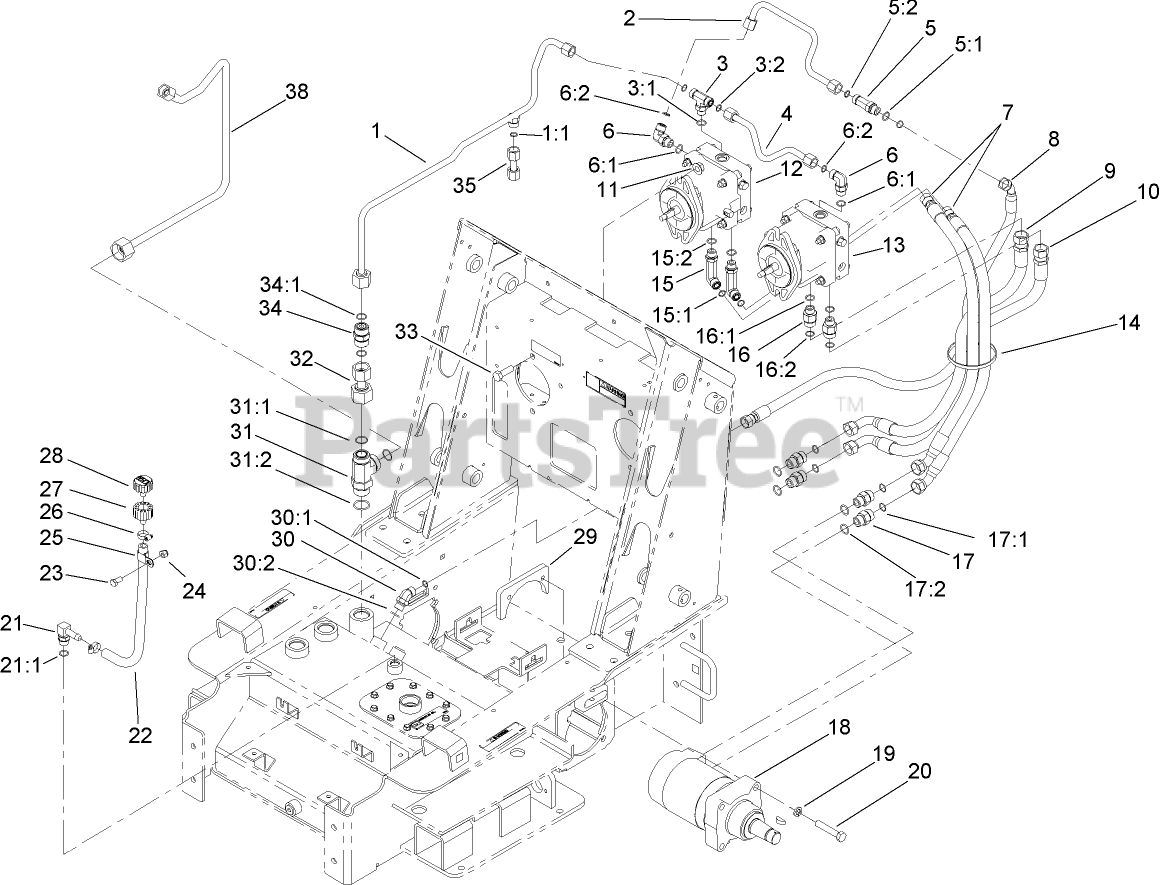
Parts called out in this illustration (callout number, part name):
1	HYD TUBE ASM
1:1	O-RING
2	TUBE-HYD
3	FITTING-HYD, TEE
3:1	O-RING
3:2	O-RING
4	TUBE-HYD
5	FITTING-TEE
5:1	O-RING
5:2	O-RING
6	FITTING-ELBOW-90 DEG
6:1	O-RING
6:2	O-RING
7	HOSE-HYD
8	HOSE-HYD
9	HYD HOSE ASM
10	HYD HOSE ASM
11	NUT-HF
12	RH HYD PUMP ASM
13	LH HYD PUMP ASM
14	TIE-CABLE
15	FITTING-ELBOW, 90 DEG
15:1	O-RING
15:2	O-RING
16	FITTING-STR
16:1	O-RING
16:2	O-RING
17	FITTING-STRAIGHT
17:1	O-RING
17:2	O-RING
18	MOTOR-HYD
19	WASHER-LOCK
20	SCREW-HH
21	FITTING-ELB 90
21:1	O-RING
22	HOSE-VENT
23	SCREW-HH
24	NUT-LOCK, NI
25	CLAMP-R
26	CLAMP-HOSE
27	ADAPTER-BREATHER
28	BREATHER
29	PLATE-MOUNTING
30	FITTING-HYD, 45 DEG
30:1	O-RING
30:2	O-RING
31	FITTING-TEE
31:1	O-RING
31:2	O-RING
32	TUBE-HYD
33	SCREW-HH
34	HYD CHECK VALVE ASM
34:1	O-RING
35	TUBE-HYD
38	HYD TUBE ASM
